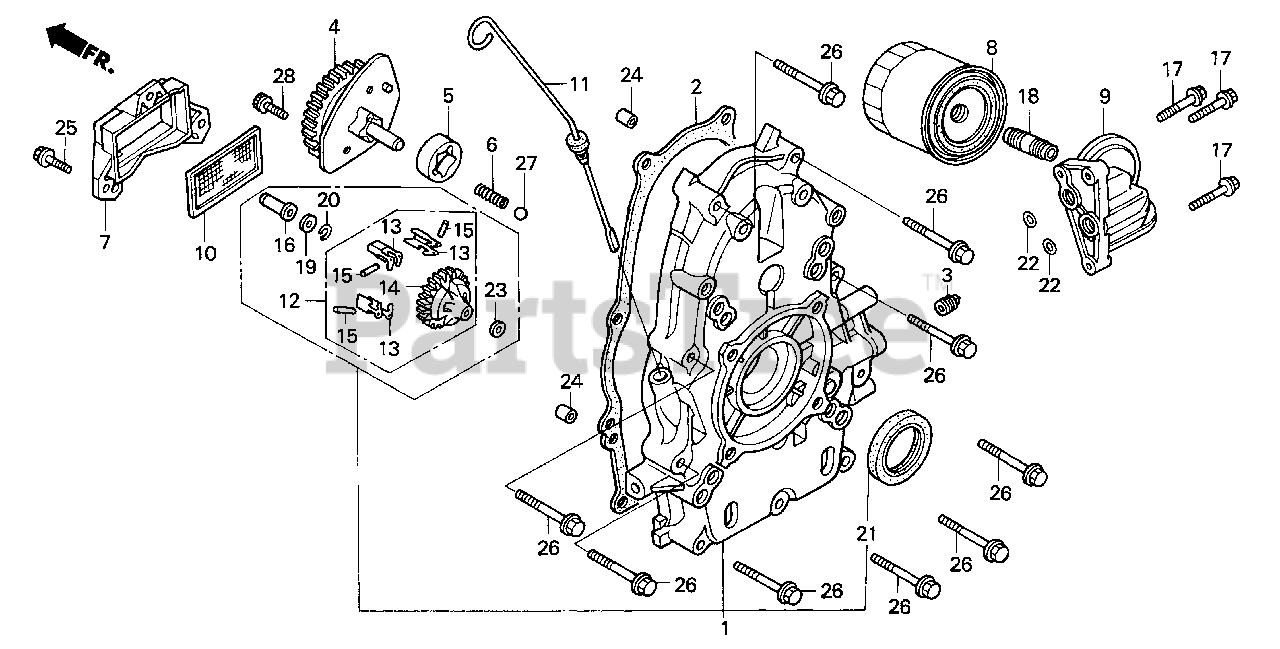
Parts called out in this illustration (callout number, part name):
1	COVER ASSY., CRANKCASE (Q-TYPE)
2	GASKET, CASE COVER
4	COVER ASSY., OIL PUMP
5	ROTOR, OIL PUMP (OUTER)
6	SPRING, RELIEF VALVE
7	COVER, OIL FILTER
8	FILTER, OIL (TOYO ROKI) (SOLD IN MULTIPLES OF 30)
8	FILTER, OIL (FILTECH INC.) (SOLD IN MULTIPLES OF 30)
8	FILTER, OIL (SOLD IN MULTIPLES OF 30)
8	FILTER, OIL (SOLD INDIVIDUALLY)
9	BASE, OIL FILTER
10	SCREEN, OIL FILTER
11	DIPSTICK, OIL
12	GOVERNOR ASSY.
13	WEIGHT, GOVERNOR
14	HOLDER, GOVERNOR WEIGHT
15	PIN, GOVERNOR WEIGHT
16	SLIDER, GOVERNOR
17	BOLT, FLANGE (6X28)
18	HOLDER, OIL FILTER
19	WASHER (6X16)
20	CLIP, GOVERNOR HOLDER
21	OIL SEAL (38X58X9)
22	O-RING (11.8X2.4)
23	WASHER, PLAIN (6MM)
24	PIN A, DOWEL (8X14)
25	BOLT, FLANGE (6X20)
26	BOLT, FLANGE (8X50)
27	BALL, STEEL (#12) (3/8)
28	BOLT, SOCKET (6X16)
